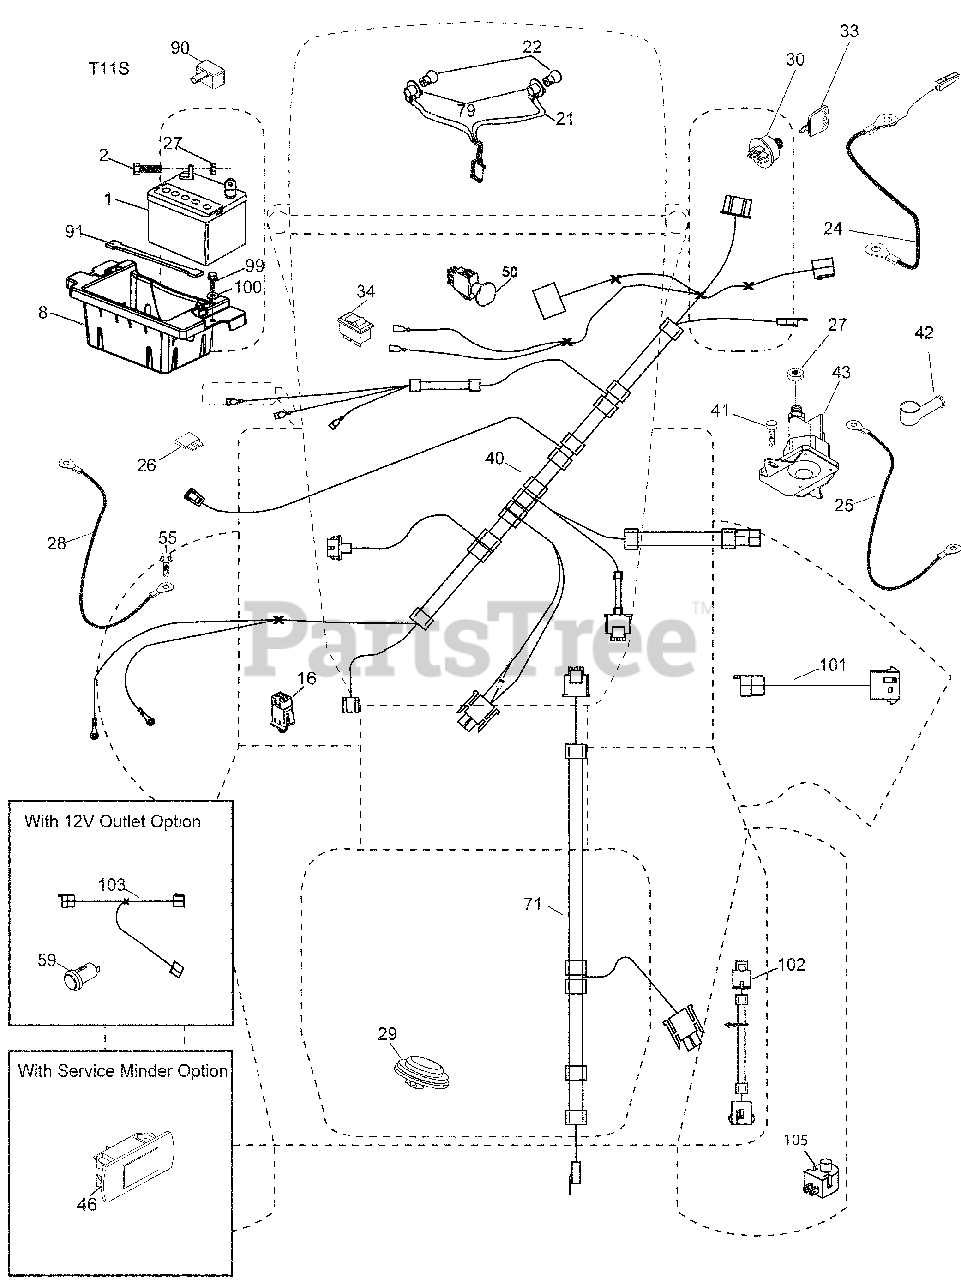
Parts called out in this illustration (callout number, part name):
1	Battery
2	Bolt Hex Hd 1/4-20 unc x 3/4
8	Battery Box
16	Switch Interlock
21	Harness Socket Light
22	Bulb, Light #1156
24	Cable Battery
25	Cable Starter
27	Nut Keps Hex 1/4-20 unc
28	Cable Ground 21" Blk 6 Ga.
29	Switch Seat
30	Switch Ign
33	Key/Chain
34	Switch Light/Reset
40	Harness Ign. Dash
41	Screw Thd Cut 1/4-20 x 1/2
42	Cover Terminal Red
43	Solenoid
46	Gauge Hourmeter
50	Switch PTO
55	Screw Thdrol 5/16-18 x 3/4
71	Harness Ign
79	Socket Asm. Bulb Twistlock
90	Cover Terminal Battery
91	Strap Battery
99	Screw Hexwsh Thdrol 1/4-20 x 3/4
100	Washer 9/32 x 7/8 x 16 Ga.
102	Harness Pigtail
105	Switch Reverse TT Pedal Control
